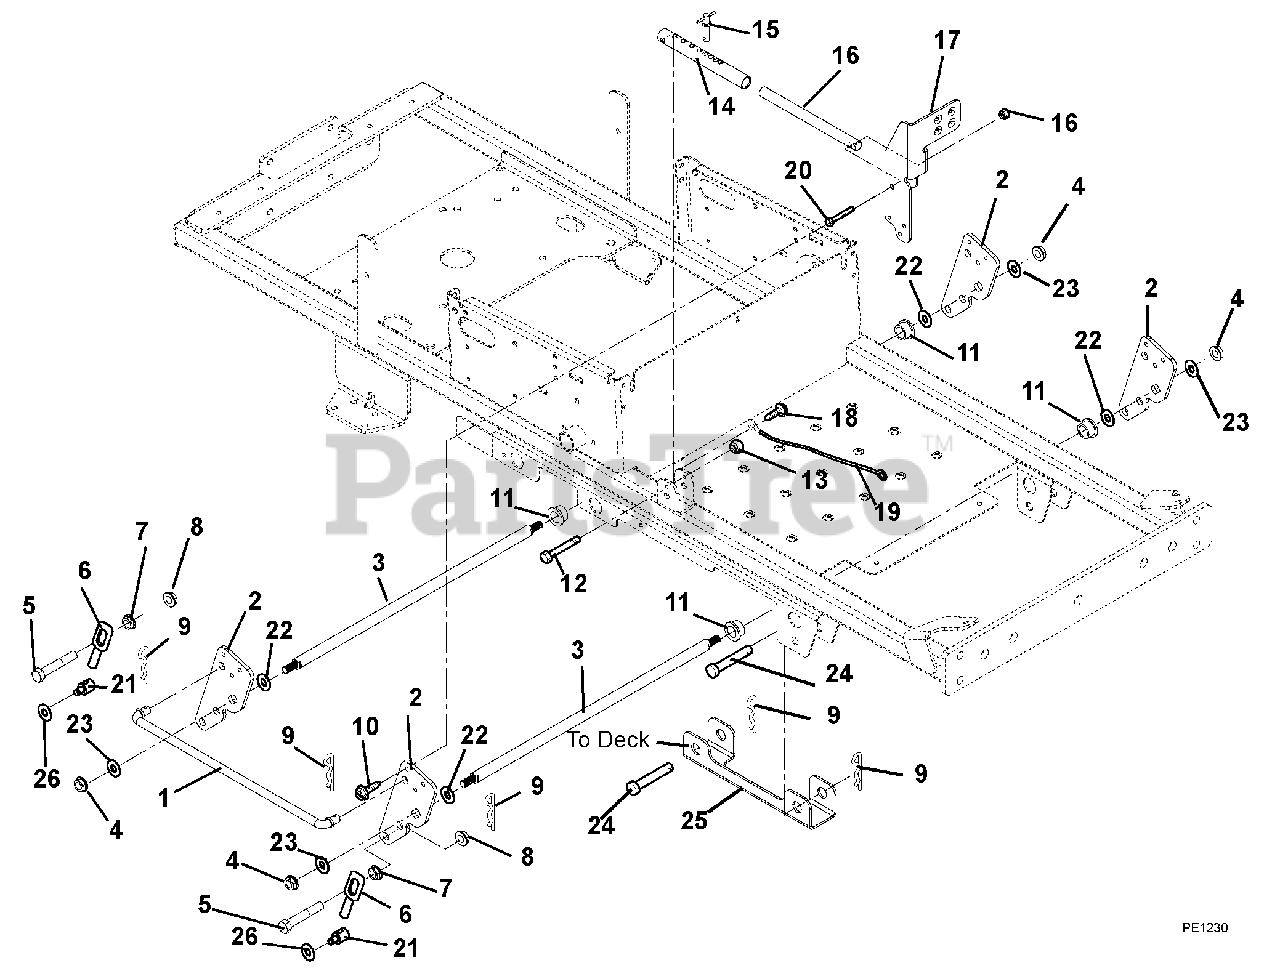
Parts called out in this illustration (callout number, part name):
1	Rod, Lift
2	Lift Arm
3	Shaft, Lift
4	Nut, Hex .250-28
5	Bolt, Hex .50-13 x 2.75 Grade 8
6	Deck Link
7	Nut, Spin Lock Flange .50-13
8	Nut .50-13 Nyloc Flange
9	Pin, Hair #16
10	Screw, Tap .31-18 x .50
11	Bushing, Flange .750 x 1.000 x .625 x 1.250
12	Bolt, Hex .38-16 x 2.00 Grade 5
13	Nut, Flange Nyloc .38-16
14	Tube, Lift Stop
15	Pin, Spring Ball .375OD x 1.50
16	Rod, Lift
17	Pedal, Foot Lift
18	Screw, Tap .25-20 x .50
19	Cable, Hood
20	Bolt, Hex .38-16 x 2.50 Grade 5
21	Trunnion
22	Washer, Flat Steel .755 x 1.375 x .062
23	Washer, Flat Steel .515 x 1.625 x .250
24	Pin, Clevis .494 x 2.50
25	Channel, Deck Lift
26	Washer, Flat-Steel .563 x 1.38 x .109
